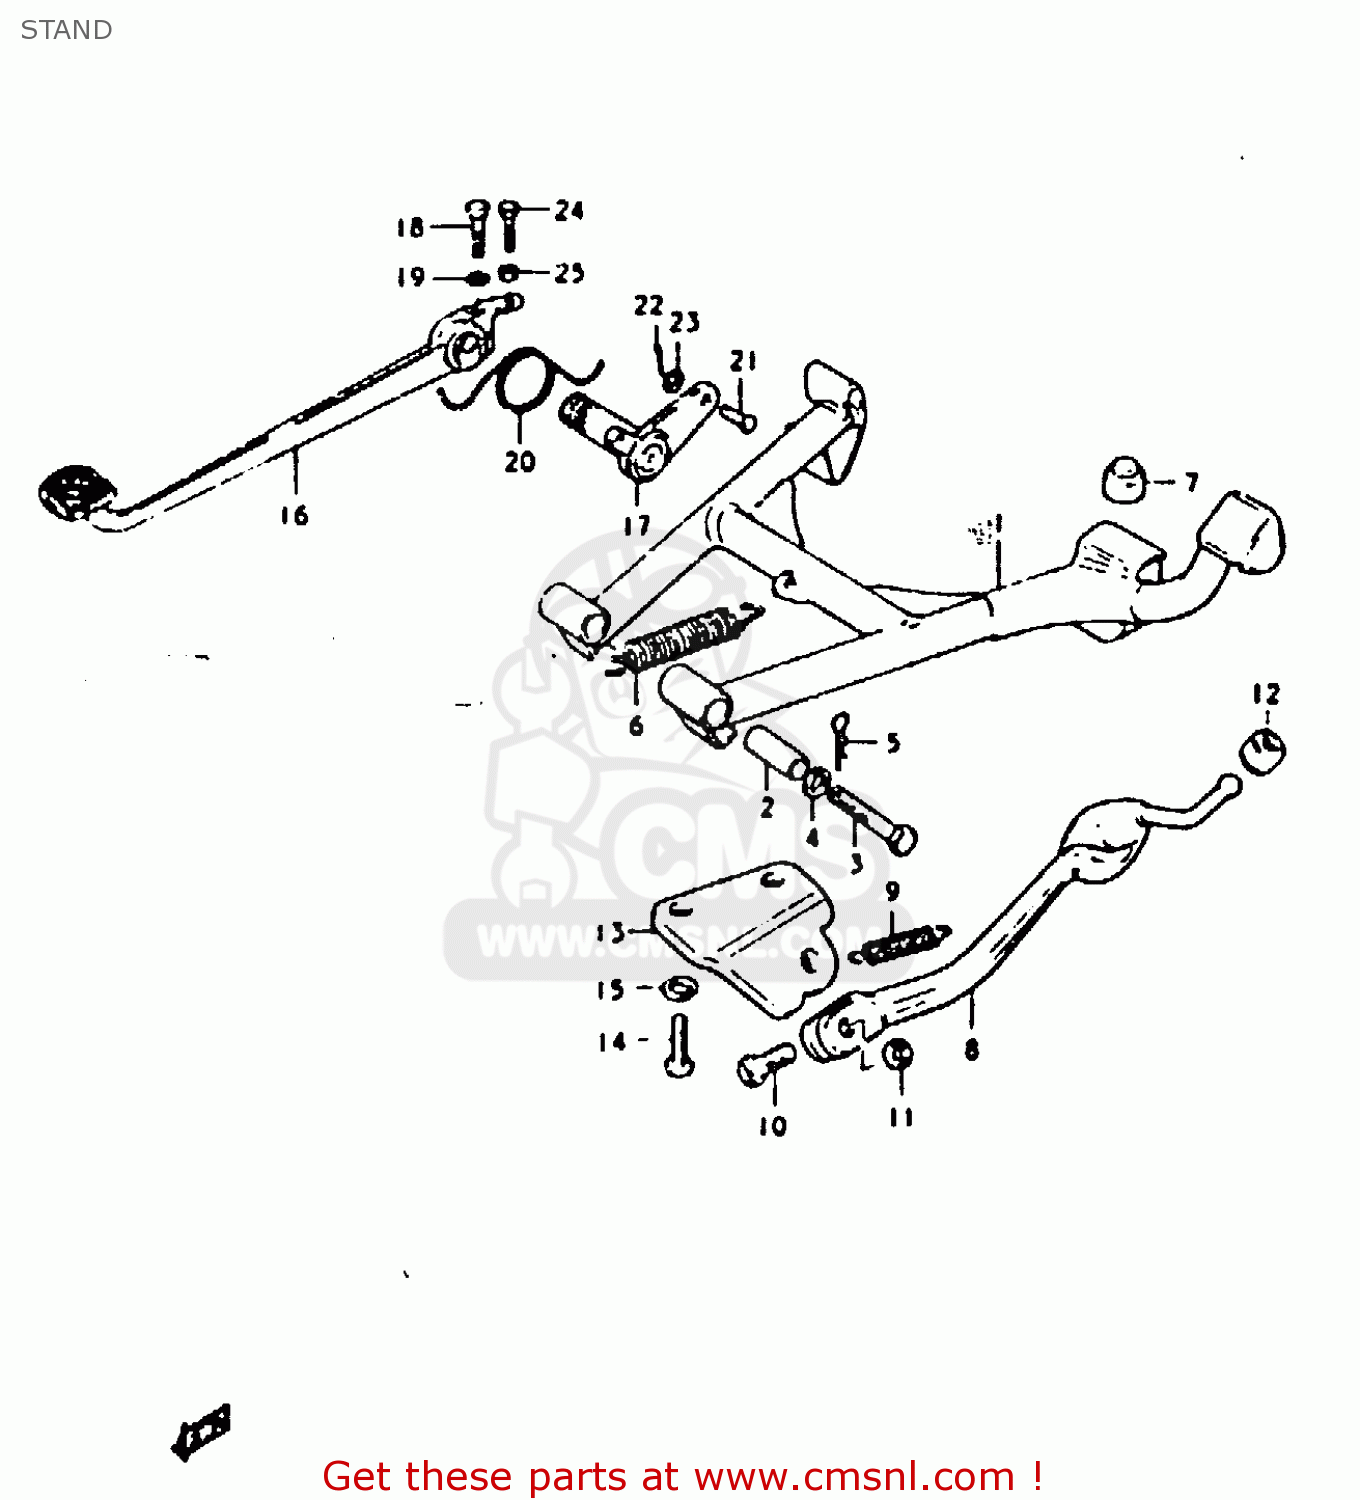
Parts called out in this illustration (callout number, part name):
1	STAND,CENTER
2	SPACER(10X16X38.8)
3	BOLT
4	LOCK WASHER
5	CLIP
6	SPRING
7	CUSHION
8	STAND,PROP
9	SPRING
10	BOLT(10X30)
11	NUT
12	CUSHION
13	BRACKET,SIDE STAND
14	BOLT
15	LOCK WASHER
16	PEDAL,BRAKE
17	ARM,BRAKE PEDAL
18	BOLT
19	LOCK WASHER
20	SPRING
21	PIN
22	PIN
23	WASHER
24	BOLT
25	NUT
